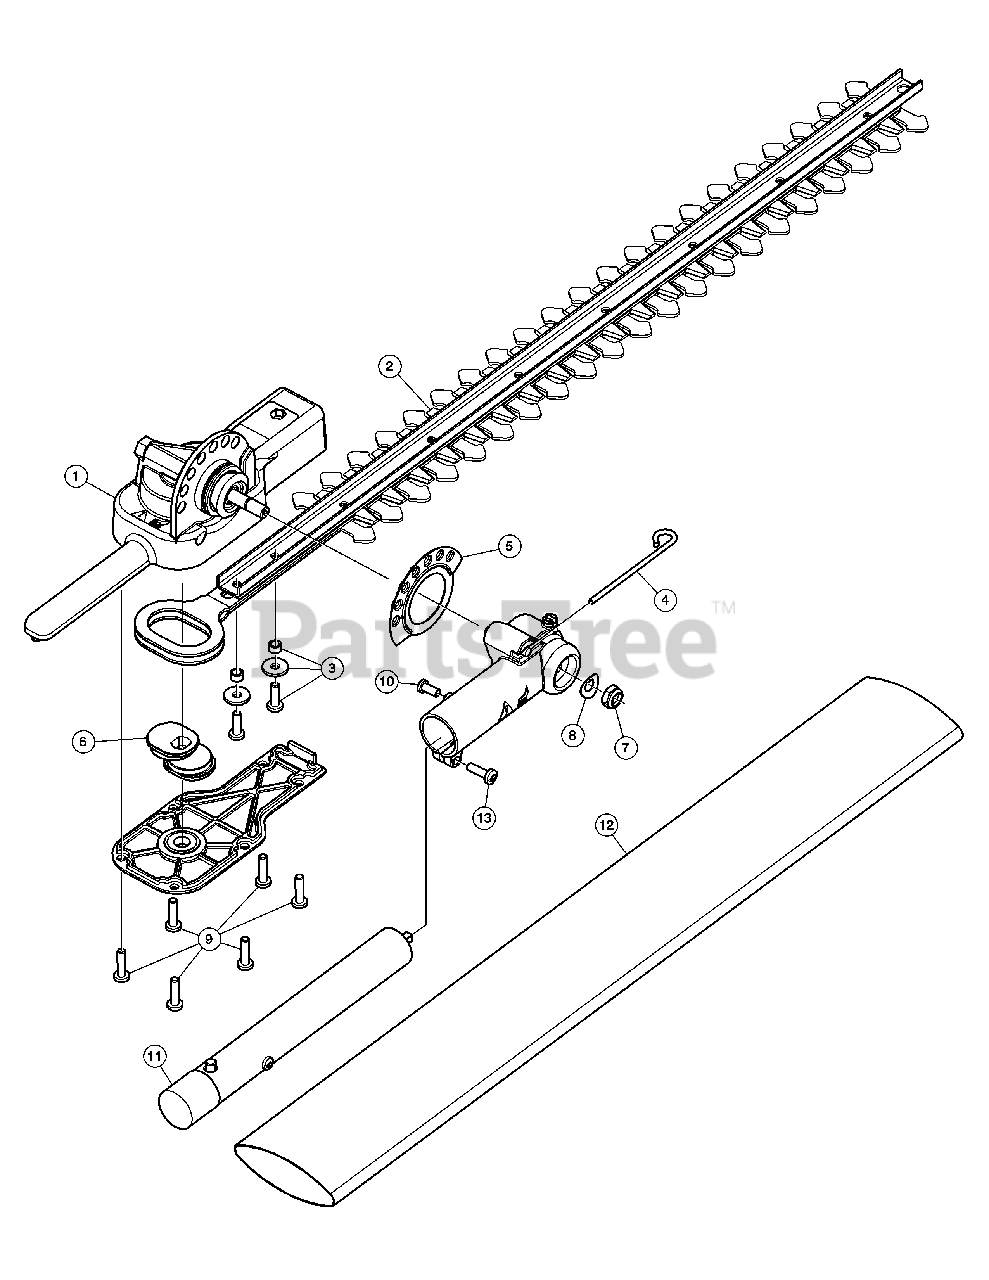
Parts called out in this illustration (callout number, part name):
1	Gearbox (includes 2 - 9)
2	Blade Assembly (includes 3)
3	Blade hardware
4	Locking Lever
8	Wavy Washer
10	Anti-Rotation Screw
11	Boom Assembly
12	Blade Guard
13	Screw
